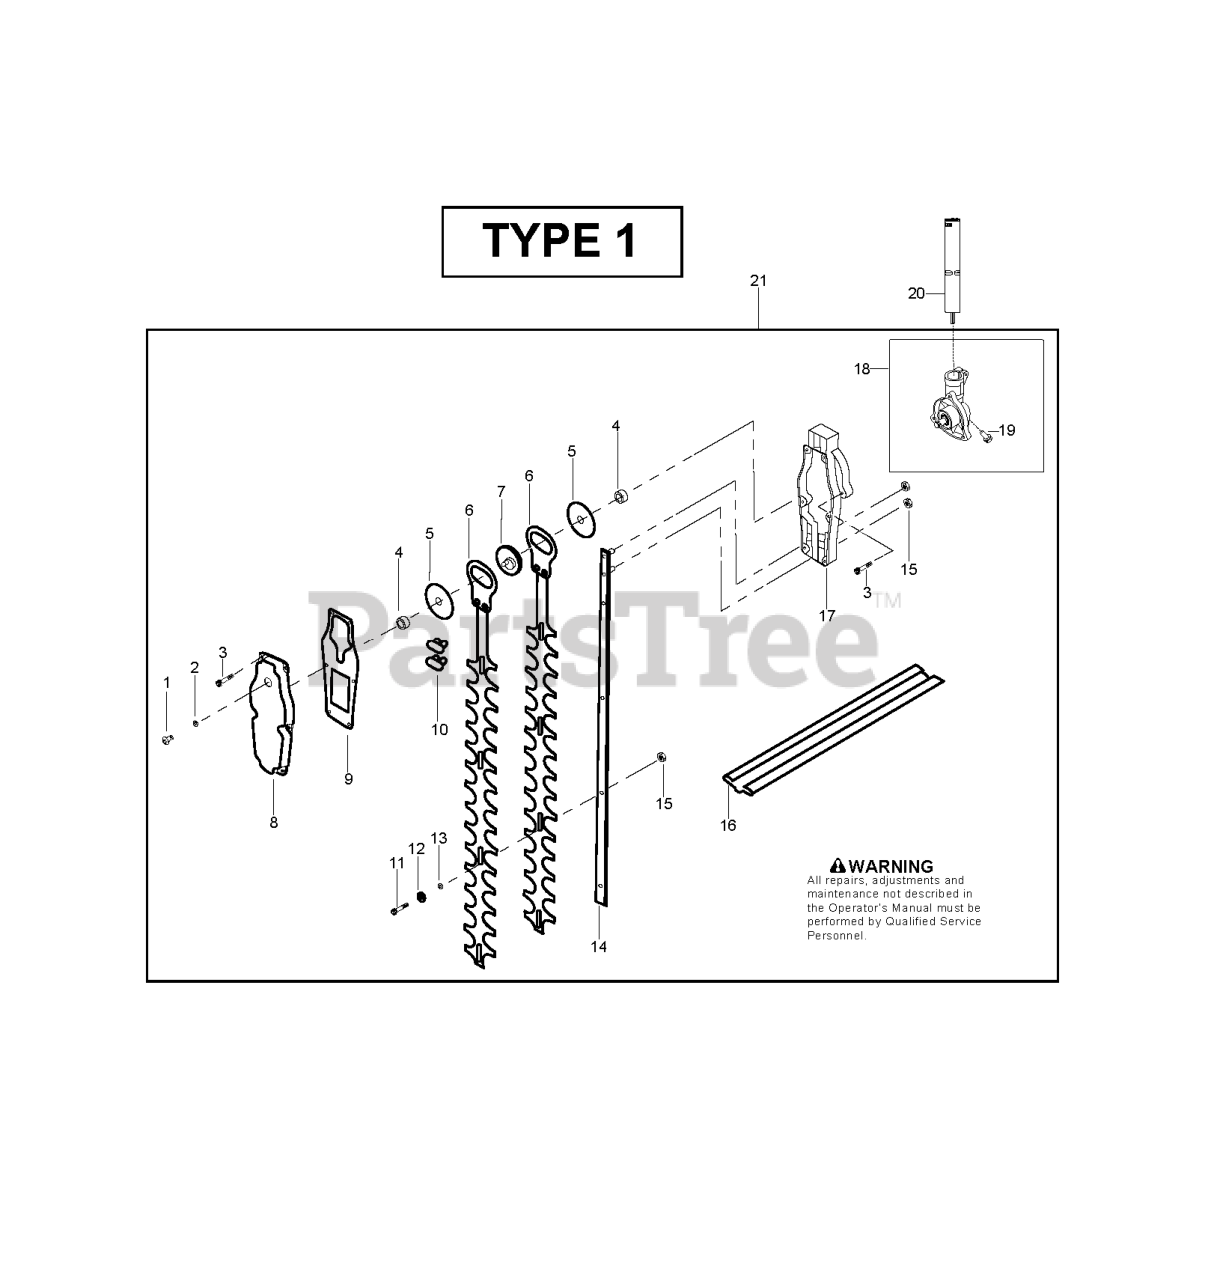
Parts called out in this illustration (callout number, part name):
3	SOCKET SCREW FLANGE KAAZ
5	FIXING PLATE
7	GEAR
9	PACKING KAAZ
10	Felt Packing
12	Conical Spring Washer (M6)
13	CUTTER WASHER KAAZ
14	BLADE GUIDE
15	U-HEXAGON NUT FLANGE KAAZ
20	ASSY TUBE HEDGE TRIMMER
21	GEAR BOX ASSY
